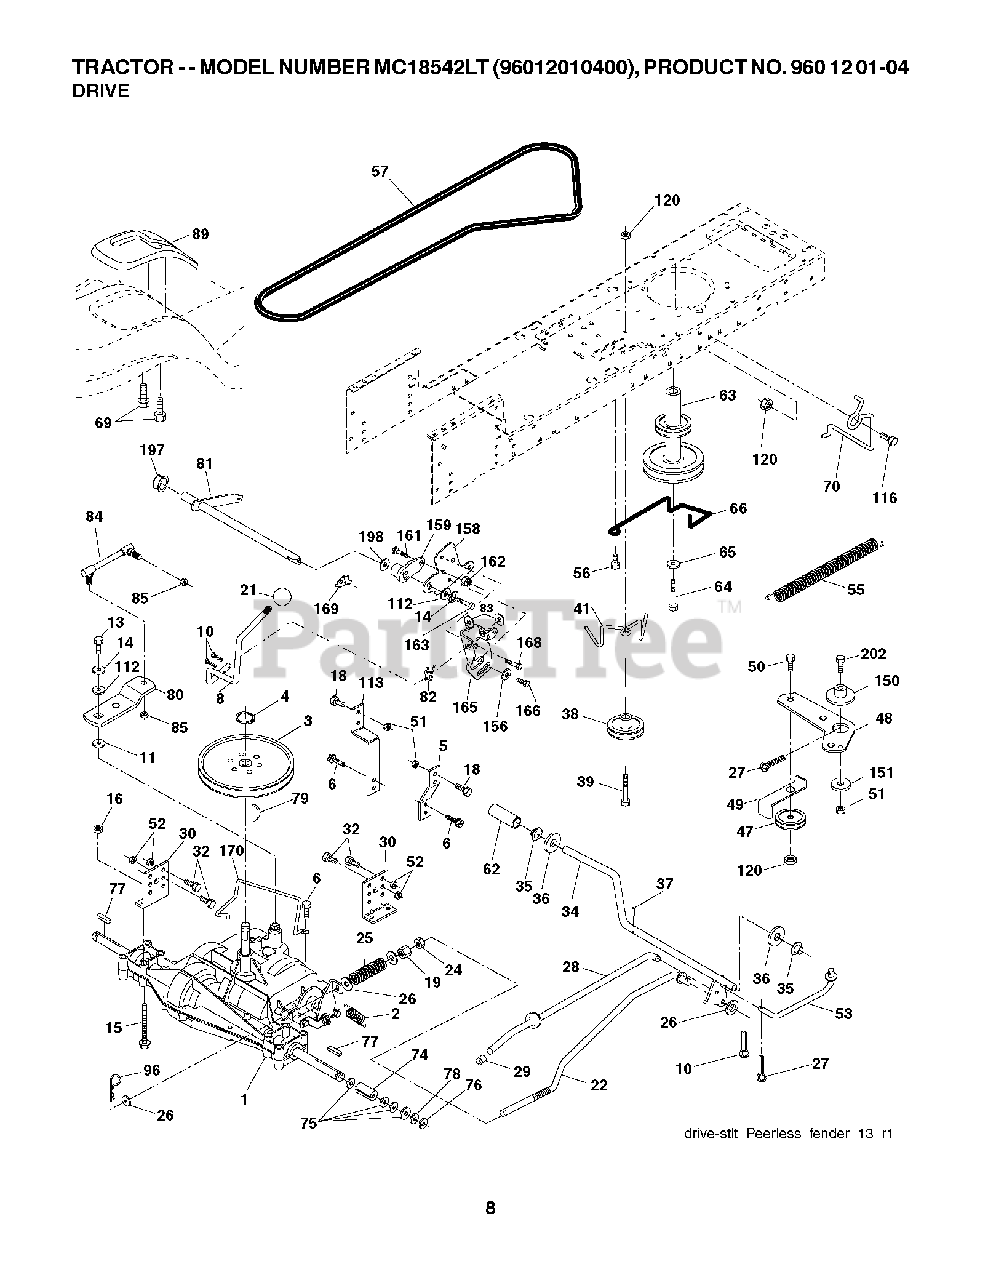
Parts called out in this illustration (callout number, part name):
1	Poulan TBD
2	SPRING,BRAKE RETURN
3	PULLEY TRANS
4	RETAINING RING LT
5	STRAP TORQUE
6	SCREW 5/16"
8	ROD SHIFT FENDER ADJUST LT
10	PIN COTTER
11	WASH-SHFT PLT LT
13	Bolt, 1/4-20 unf Grade 8 w/Patch
14	LOCKWASHER
15	Hex Flange Bolt, 5/16-18 X 3.75
16	NUT.71038.31-18.HEX.NYLOCK
19	NUT
21	KNOB T (1/2-HOLE)
22	ROD BRAKE
24	NUT
25	SPRING ROD LT
27	COTTER PIN
28	ROD, PARKING BRAKE
29	PLUNGER CAP
30	BRKT, TRNSXLE MNT 20"
32	BOLT
34	SHAFT, FOOT PEDAL
35	BEARING.NYLON
36	WASHER LT
38	PULLEY IDLER COMPOSITE
41	KEEPER, BELT IDLER
47	Idler Pulley
48	BELLCRANK, CLUTCH
49	RETAIN BELT
50	BOLT.3/8-16X1.50
51	LOCKNUT
52	LOCKNUT
53	LINK.CLUTCH.7.66.2005
55	SPRING, RETURN LT
56	SCREW.3/8-16
57	BELT, V GROUND DRIVE 95 25
63	ENGINE PULLEY
64	BOLT HEX 7/16-20X4-1/4"
65	LOCKWASHER
66	KEEPER BELT ENGINE
69	SCREW.HI-LO.CONSOLE
70	KEEPER BELT ENG
74	SPACER AXLE
76	E-RING LT
77	SQUARE KEY
79	KEY STD (1373) DANA
80	ARM SHIFT
81	SHAFT ASM CROSS TAPERED PMST/2
82	SHIFT SPRING
83	WASHER
84	LINK.TRANSAXLE.PMST/DANA.20"
85	NUT LOCK CENTER 1/4 -28 FNTHD
89	CONSOLE SHIFT STLT
112	WASHER LT
113	STRAP TORQUE LH LT
120	NUT LOCK FLG 3/8-16 UNC
150	SPACER, RETAINER
151	WASHER 12/32X2X10GA
156	WASHER.SRRTD.5/16
158	BRACKET
159	HUB.SHIFT
161	BOLT
162	NUT.CROWNLOCK.1/4
165	RP BRACKET
168	BOLT.SHOULDER.5/16-18X
169	PLATE.FASTENING.CROSS.SHAFT
170	KEEPER BELT T/A
197	NYLINER SNAP 5/8" ID
198	WASHER.NYL.7/8IDX.105"HYD CR
202	BOLT
